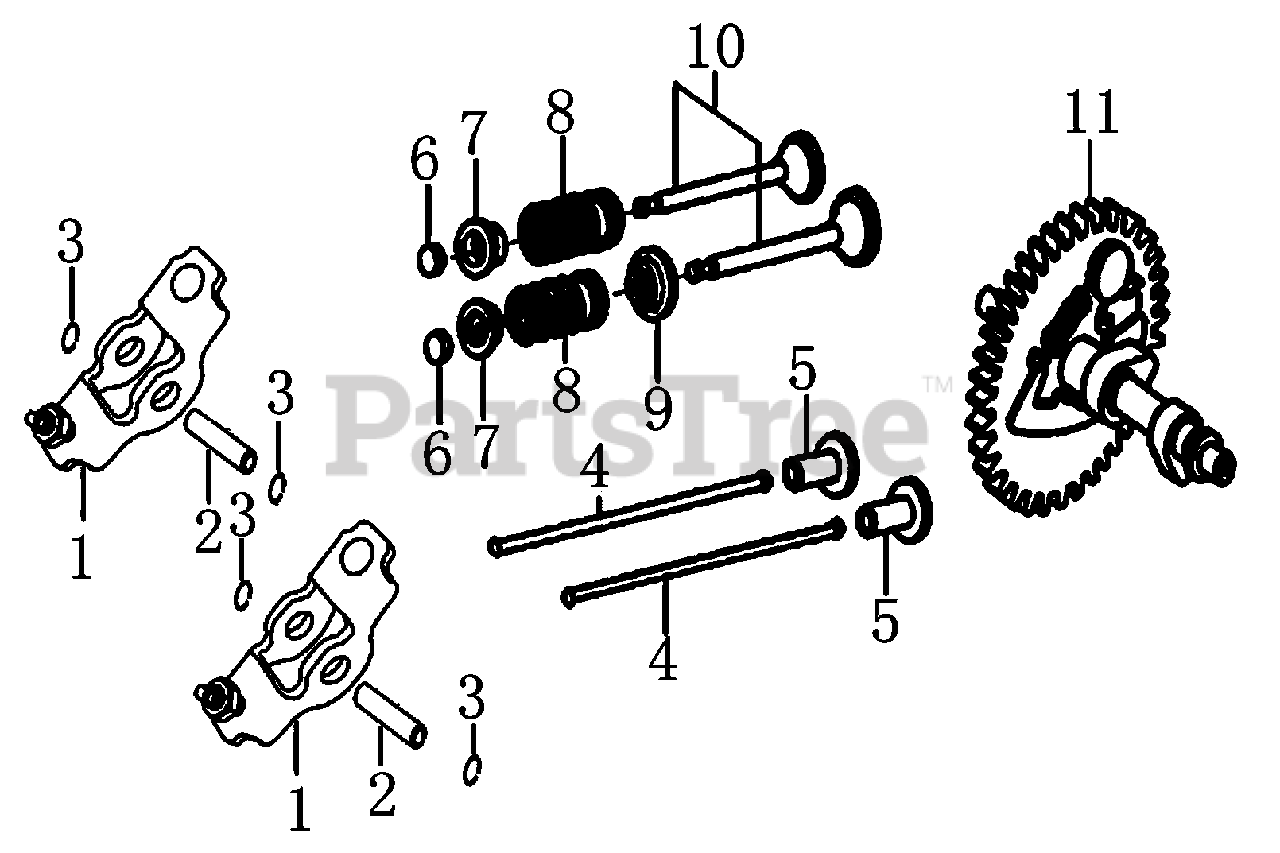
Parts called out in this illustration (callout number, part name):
1	ARM, ROCKER
2	SHAFT, VALVE ROCKER SHAFT
3	CIRCLIP, LOCKER
4	ROD, PUSH
5	LIFTER, VALVE
6	ROTATOR, VALVE
7	RETAINER, VALVE SPRING
8	SPRING, VALVE
9	SEAL, GUIDE
10	VALVE SET
11	CAMSHAFT ASSY.
